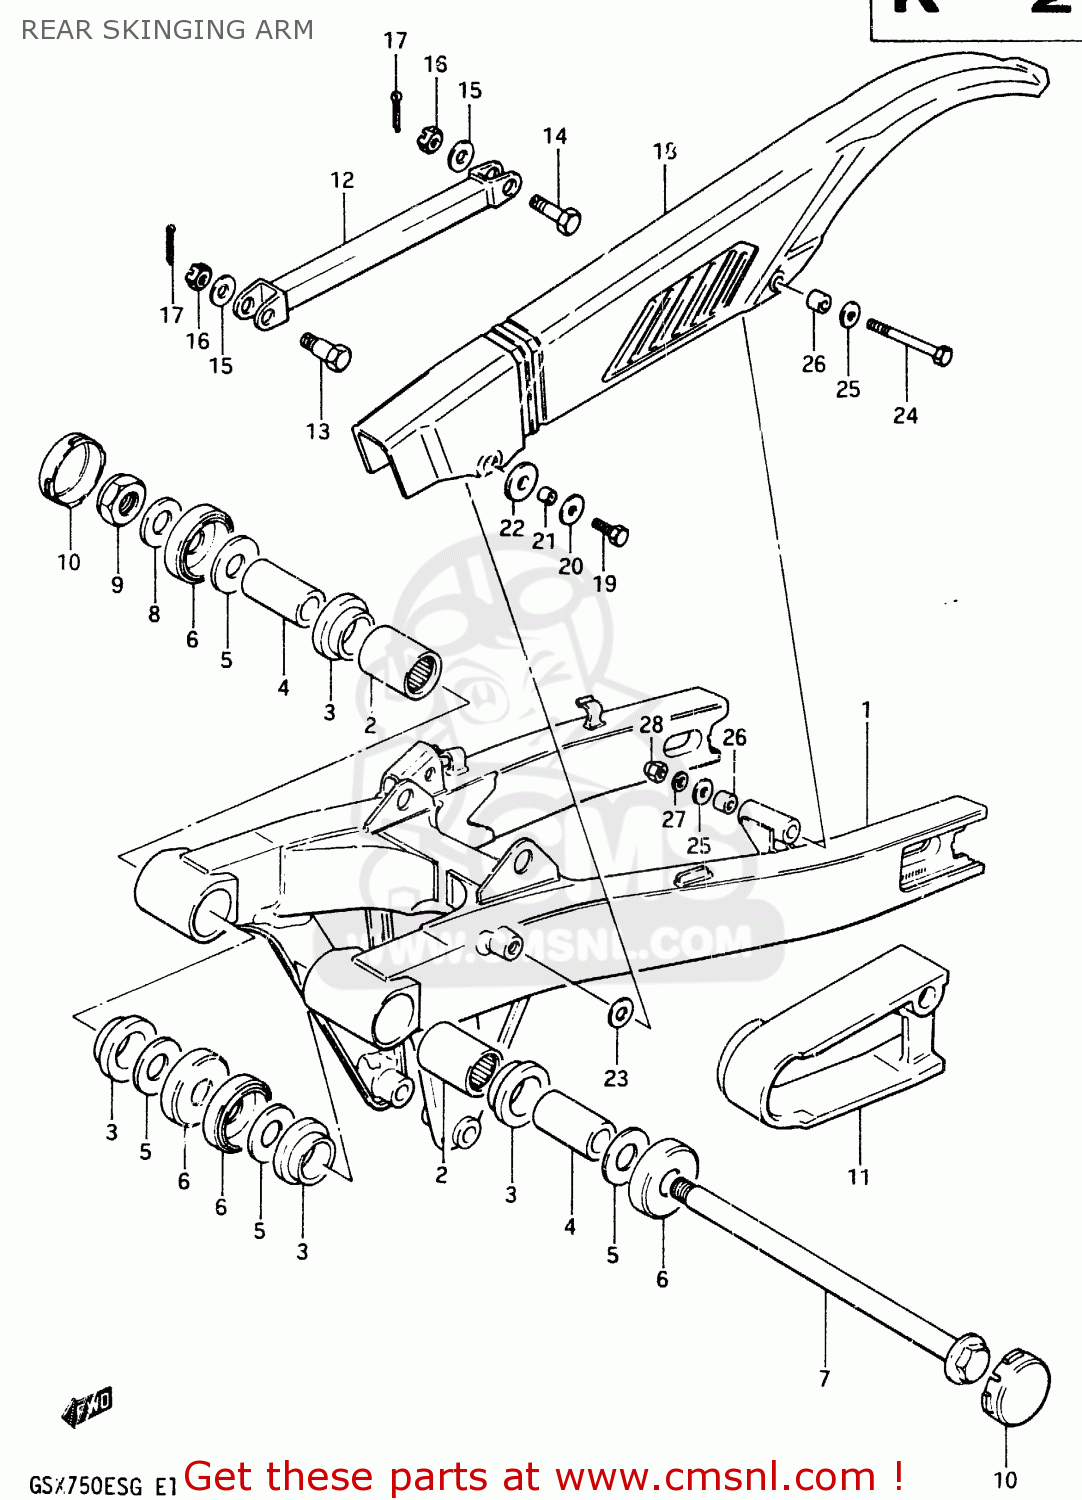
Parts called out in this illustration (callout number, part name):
1	SWING ARM ASSEMBLY,REAR
2	BEARING(25X33X30)
3	BUSHING
4	SPACER,RR SWGARM PIVOT
5	WASHER
6	COVER,RR SWINGINGARM PIVOT
7	SHAFT,REAR SWING ARM
8	WASHER
9	NUT
10	CAP,PIVOT
11	BUFFER,DEFENSE
12	TORQUE LINK,REAR
13	BOLT
14	BOLT(10X39)
15	WASHER 10MM
16	NUT
17	PIN 20X20
18	CASE,CHAIN
19	BOLT 6X16
20	WASHER (6.5X22X1.6)
21	SPACER
22	WASHER
23	WASHER (6.5X22X1.6)
24	BOLT 6X60
25	WASHER(6.5X18X1)
26	SPACER
27	WASHER,LOCK
28	NUT 6MM
